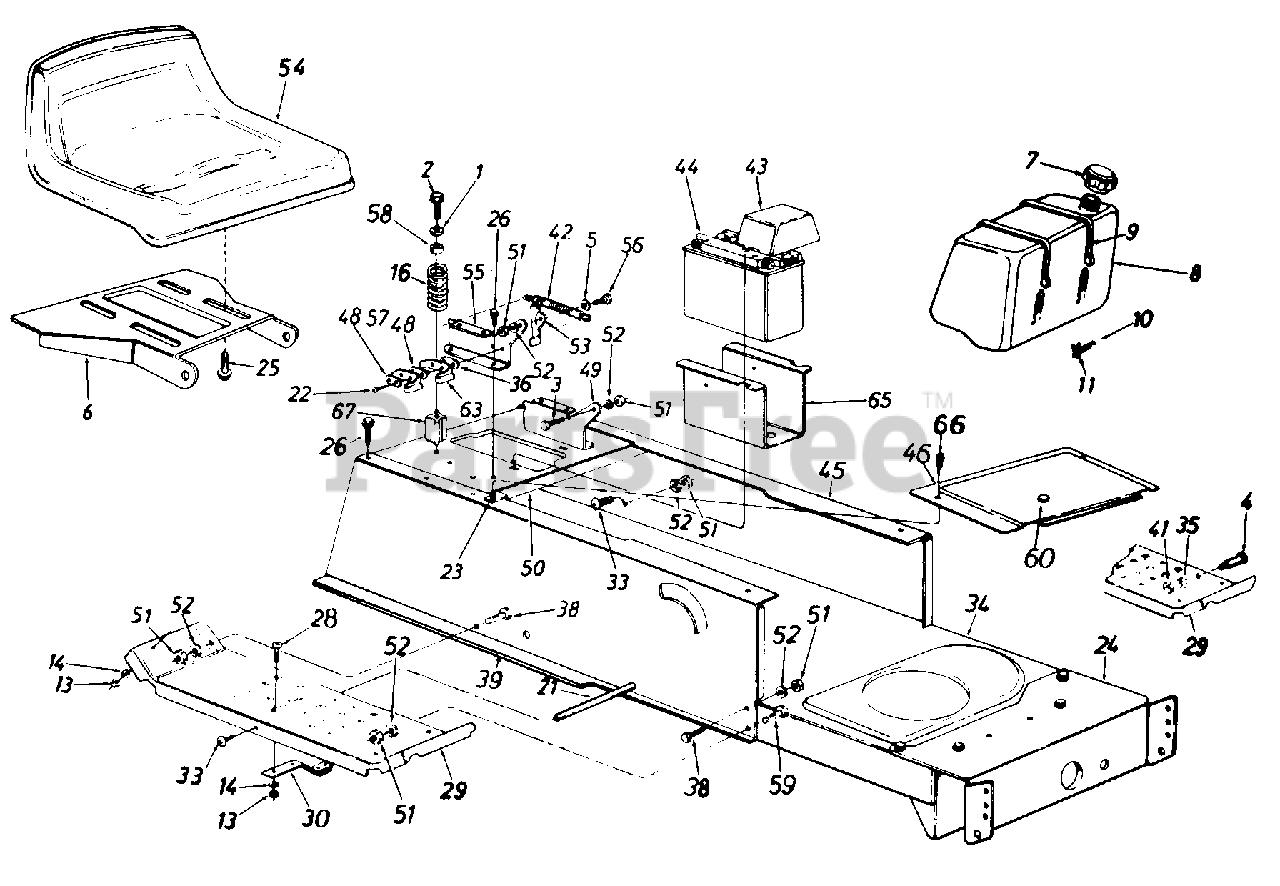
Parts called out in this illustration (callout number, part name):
1	Fl-Wash. .344" I.D. x .875"
2	Hex Wash. Hd. Tap Scr. 5/16-18 x 3.251' Lg.
3	Shld. Bolt 437" Dia. x .162"
4	Shld. Bolt .50" Dia. x .84"
5	Spr-Wash. 445" l.D. x .75
6	Seat Pivot Bracket
7	Fuel Cap
8	Fuel Tank
9	Tie Strap
10	Fuel Line
13	Hex Nut 1/4-20 Thd.
14	L-Wash. 1/4" I.D.
16	Compression Spring
21	Running Board Rod
22	Hex Wash. Hd. AB-Tap Scr. #8 x .50" Lg.
23	Speed Nut #10Z
24	Front Pivot Brkt.
25	Hex Tap Scr. 3/8-16 x .75"
26	Hex Wash. Hd. AB-Tap Scr. 5/16 x .75" Lg.
28	Carriage Bolt 1/4-20 x .62n
29	Running Board
30	Blade Brake Ass'y.
33	Truss Mach. Scr. 5/16-18 x .75" Lg.
34	Lower Frame
35	L-Wash. 3/8" I.D.
36	Insulator Boss Plate
38	Hex Bolt 5/16-18 x .75" Lg.
39	Upper Frame-R.H.
41	Hex Nut 3/8-16 Thd.
42	Extension Spring 5.31n Lg.
43	Battery Cover
44	12-V Battery (275 Cold Crank Amps)
45	Upper Frame-L.H.
46	Shift Cover
48	Insulator Plate
52	L-Wash. 5/16n l.D.
53	Seat Lift Brkt.
56	Shld. Bolt 437n Dia. x .268n
57	Spring Switch
59	Hex Wash. TT-Tap Scr. 5/16-18 x 7l8n Lg.
60	Snap Bushing
63	Safety Switch
65	Battery Tray
66	Truss Mach. B-Tap Scr. #10 x 5n Lg.
67	Spring Spacer
